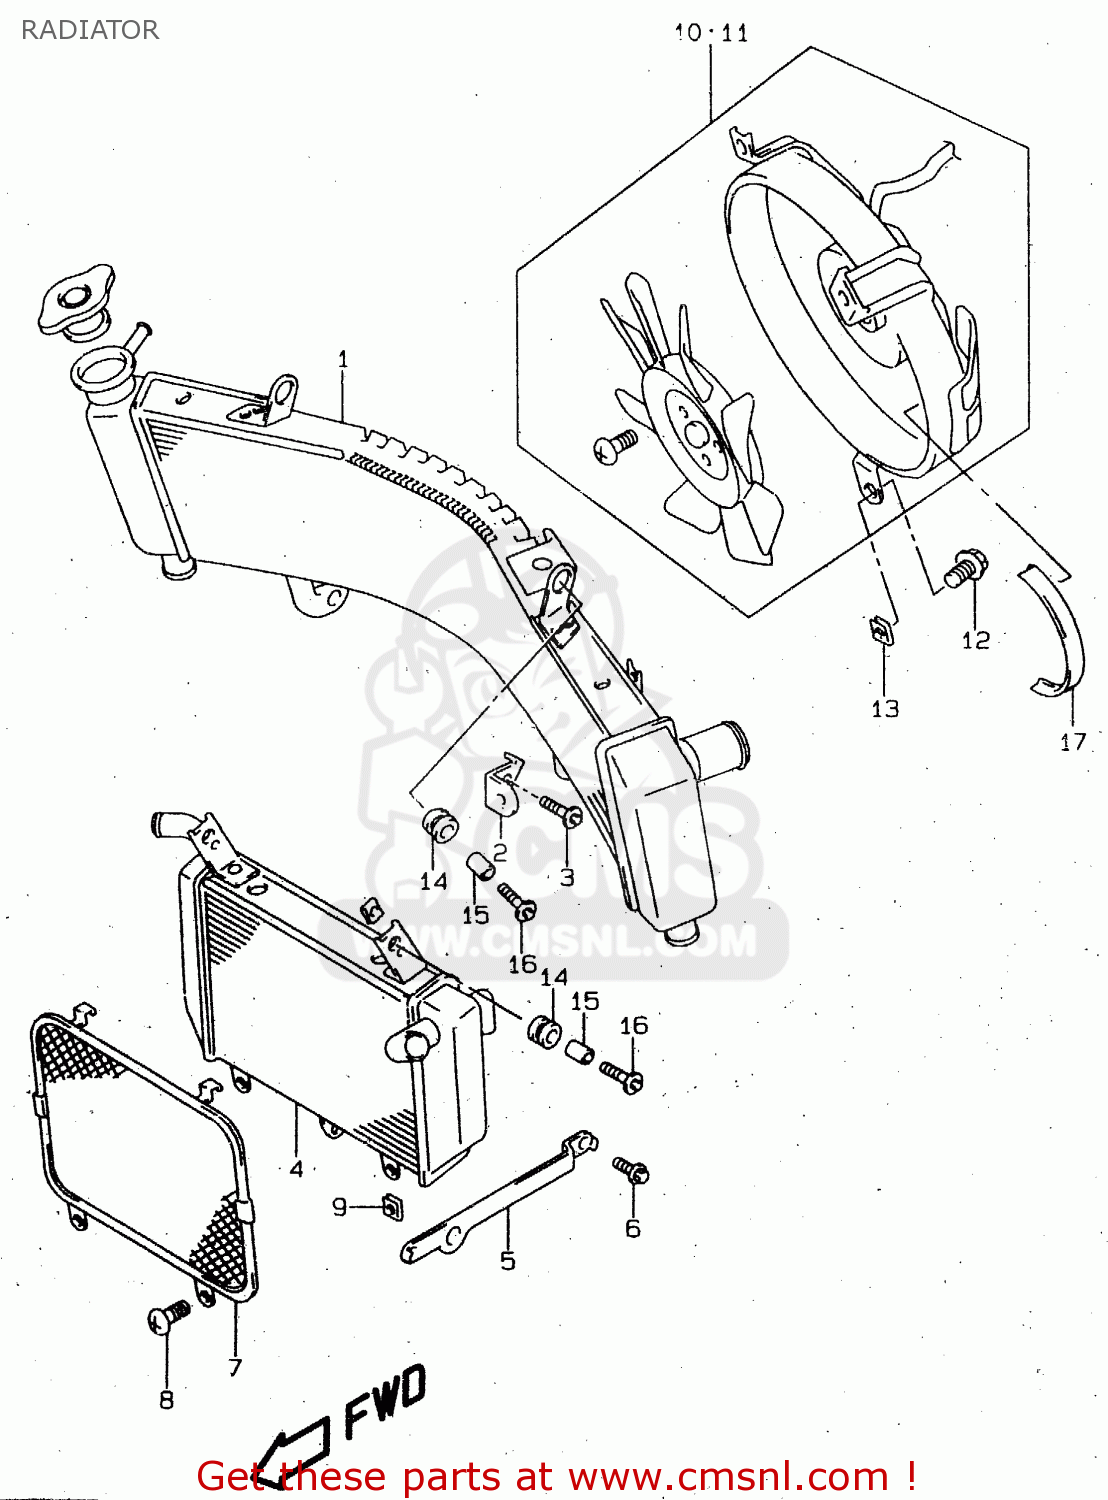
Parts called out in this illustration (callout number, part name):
1	RADIATOR ASSEMBLY,WATER,UPPER
2	BRACKET,RADIATOR UPR
3	BOLT
4	RADIATOR ASSEMBLY,WATER,LOWER
5	BRACKET,RADIATOR LWR
6	BOLT
7	COVER,RADIATOR
8	SCREW 6X12
9	NUT
10	FAN ASSY,RADIATOR,R
11	FAN ASSY,RADIATOR,L
12	BOLT
13	NUT
14	CUSHION
15	SPACER(6.5X10X12)
16	BOLT(6X25)
17	MOLDING,FAN SHROUD,L,L(L:165)
